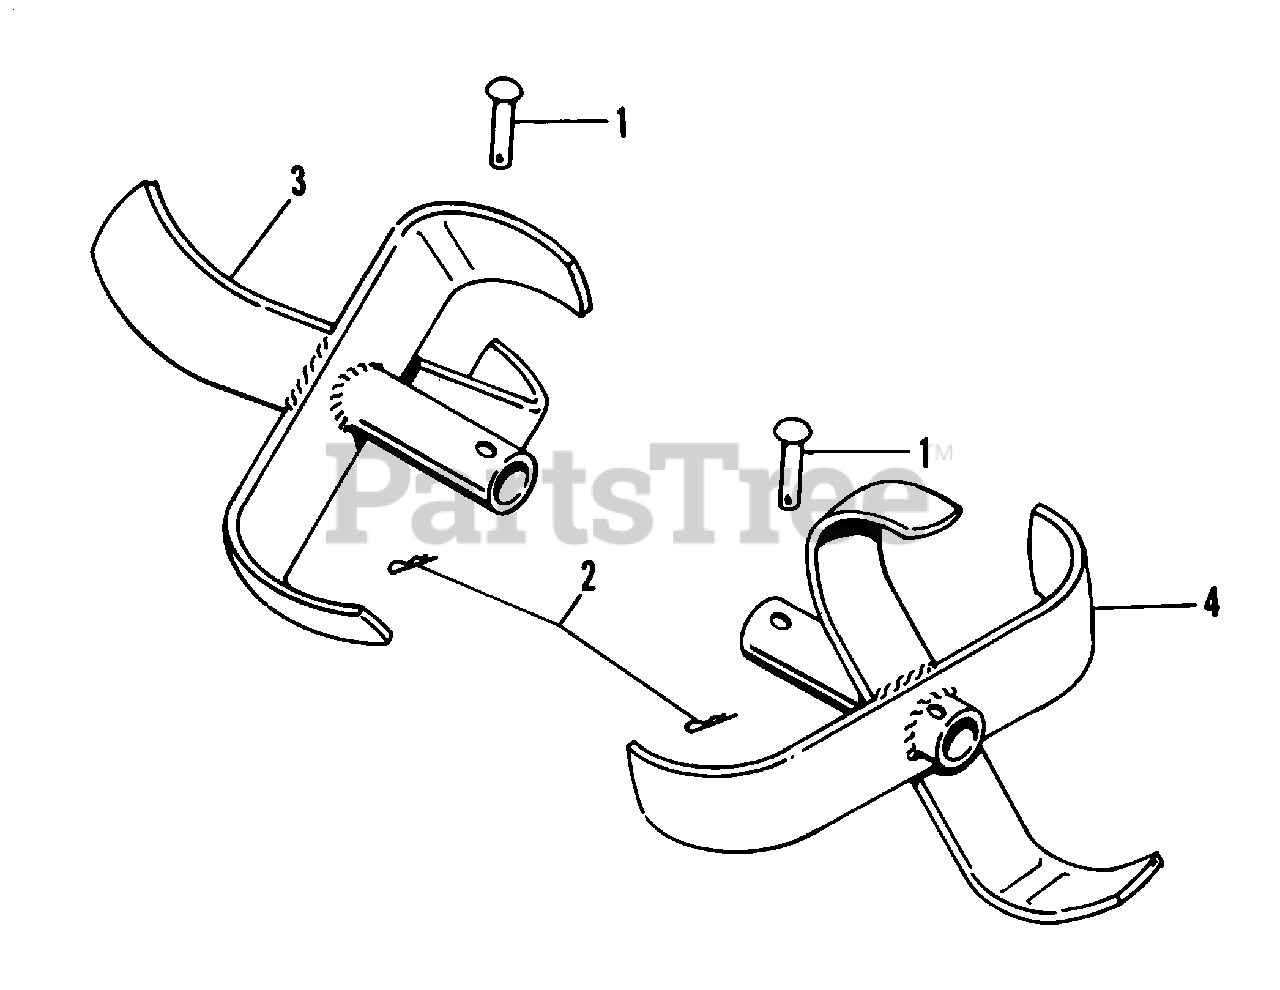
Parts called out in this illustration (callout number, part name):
1	PIN
2	PIN, Quick, 1-7/8
3	TINE ASSY, R.H., Outer
4	TINE ASSY, L.H., Outer
